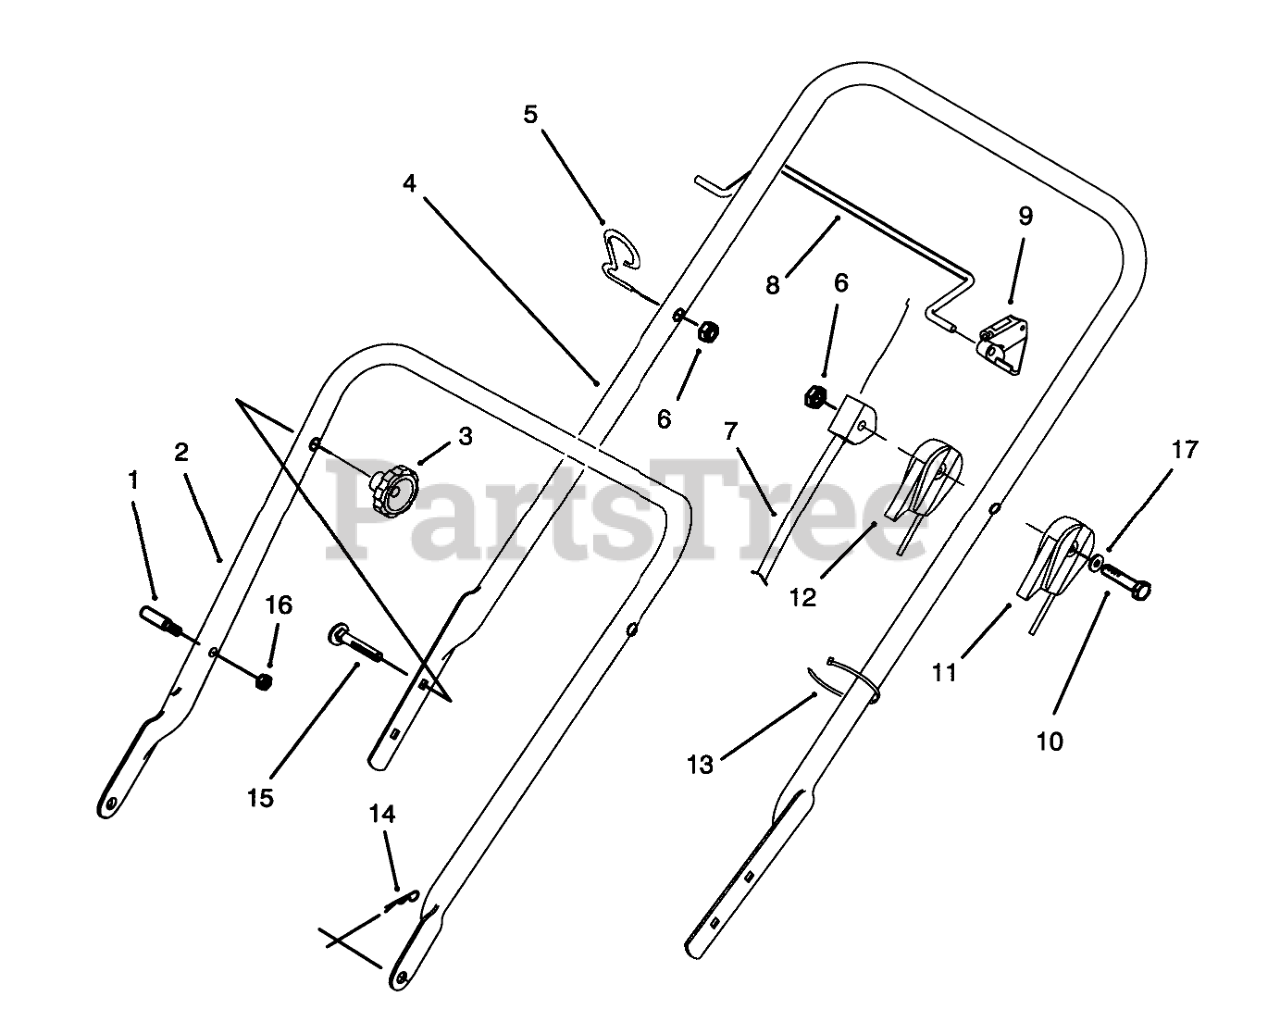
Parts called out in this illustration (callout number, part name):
1	HANDLE PIN
2	LOWER HANDLE ASM
4	UPPER HANDLE
5	GUIDE-ROPE
6	NUT-LOCK, NI
7	BRAKE CONTROL
8	Bar-Control
9	STOP-PIVOT
10	SCREW-HH
11	TRACTION CONTROL
12	THROTTLE CONTROL
13	TIE-CABLE
14	PIN-COTTER, HAIR
15	SCREW
16	NUT-LOCK, NI
17	WASHER-FLAT
